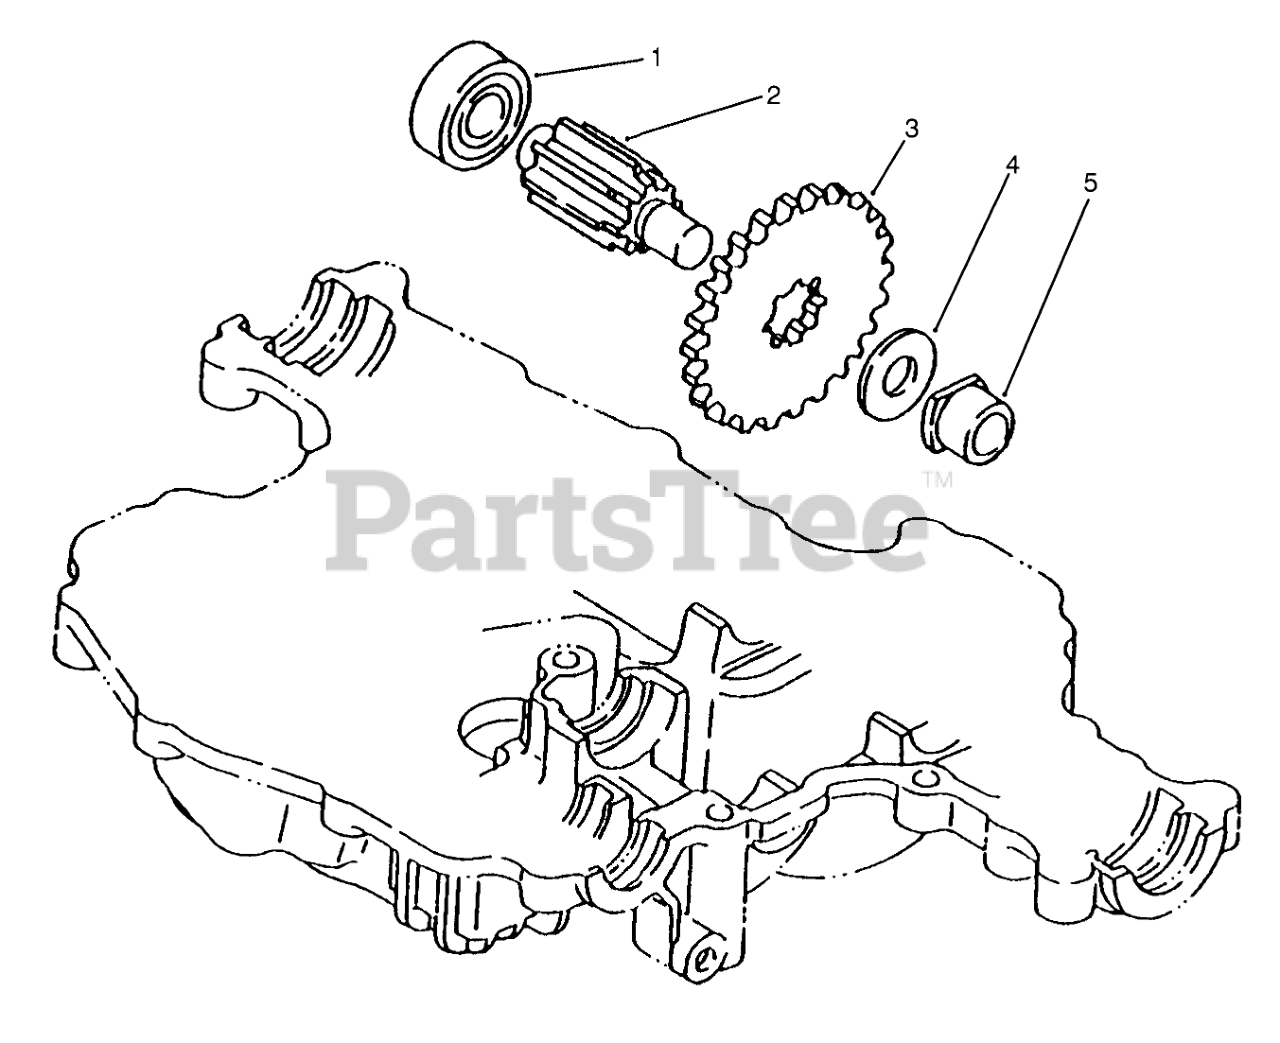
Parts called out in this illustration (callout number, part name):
1	BEARING
2	SHAFT - FINAL PINION
3	GEAR-FINAL SHAFT
4	WASHER
5	BUSHING
